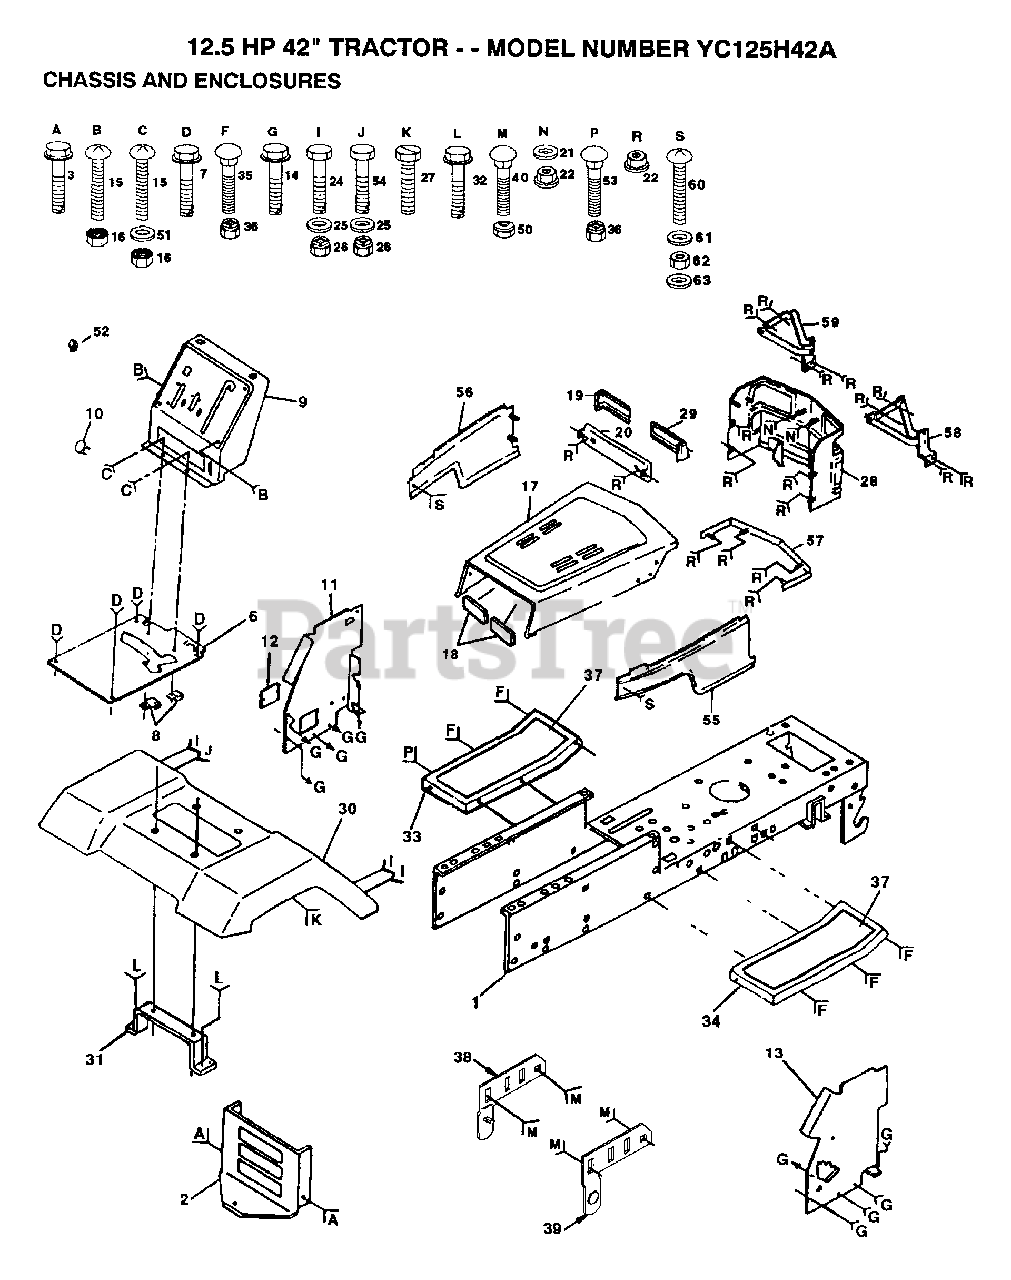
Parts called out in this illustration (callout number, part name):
1	CHASSIS ASM
3	SCREW
7	SCREW LT
8	"CLIP,INSULATOR"
10	PLUG BUTTON T
11	PANEL DASH LH
12	COVER ACCESS
14	SCREW LT
15	SCREW
21	WASHER PM
22	PAL NUT LT
25	WASHER
27	SCREW LT
31	BRKT FENDER
32	SCREW
35	BOLT
37	FOOTREST PAD
38	PIVOT BRKT LH
39	PIVOT BRKT RH
50	NUT
51	WASHER
52	PLUG DOME
55	SIDE PANEL ASM RH
56	SIDE PANEL ASM LH
57	STRAP ASM GRILL
58	"HINGE,HOOD,RH T"
59	"HINGE,HOOD,LH T"
60	"SCREW,SPECIAL"
62	RETAINER
63	"GROMMET,PLASTIC"
